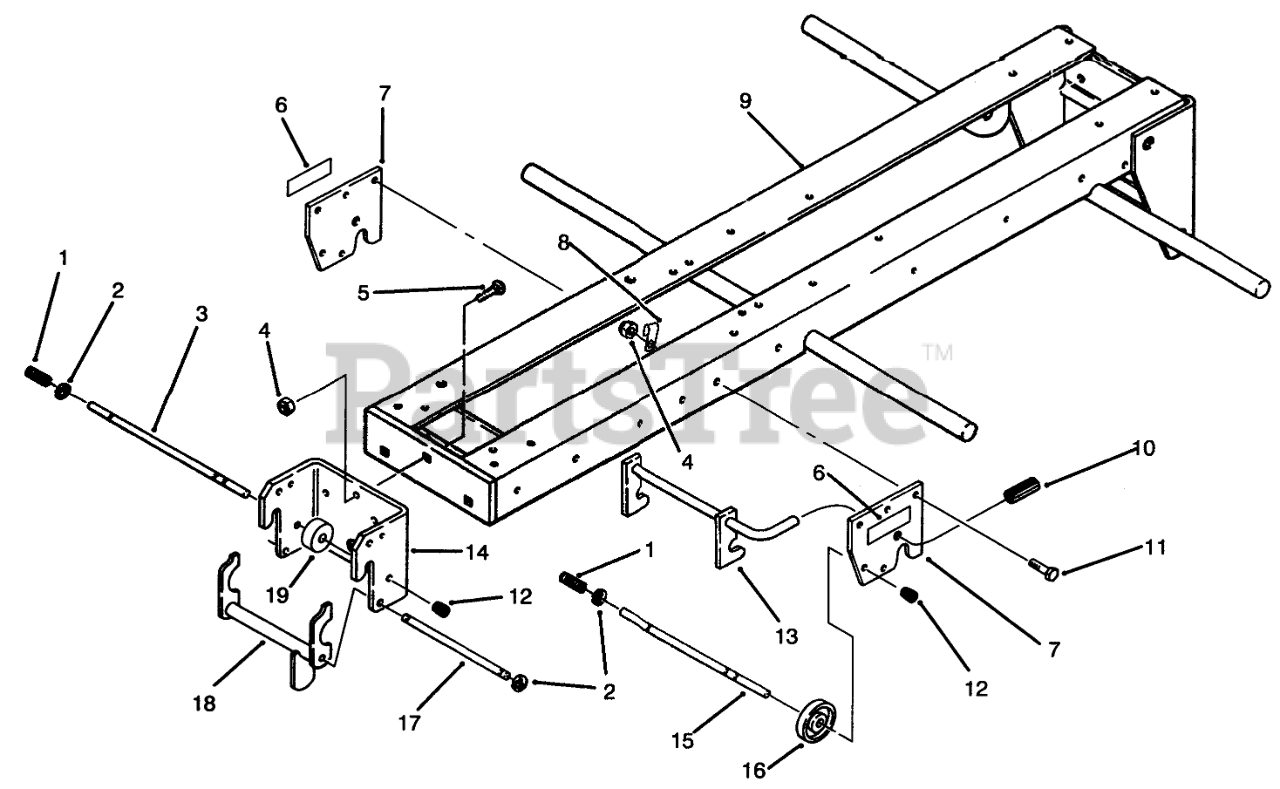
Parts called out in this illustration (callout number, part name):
1	SPRING
2	RING-RETAINING
3	ROD-LOCK
4	NUT-LOCK, NI
5	BOLT-CARR
6	DECAL-ATTACH A-MATIC
7	Hitch Plate
8	CLIP
9	WELD FRAME R
10	GRIP
11	SCREW-HH
12	CAP-ROD, PLUNGER
13	MID HITCH ASM
14	Front Hitch
15	ROD-LOCK
17	ROD-LATCH PIVOT
18	LATCH
